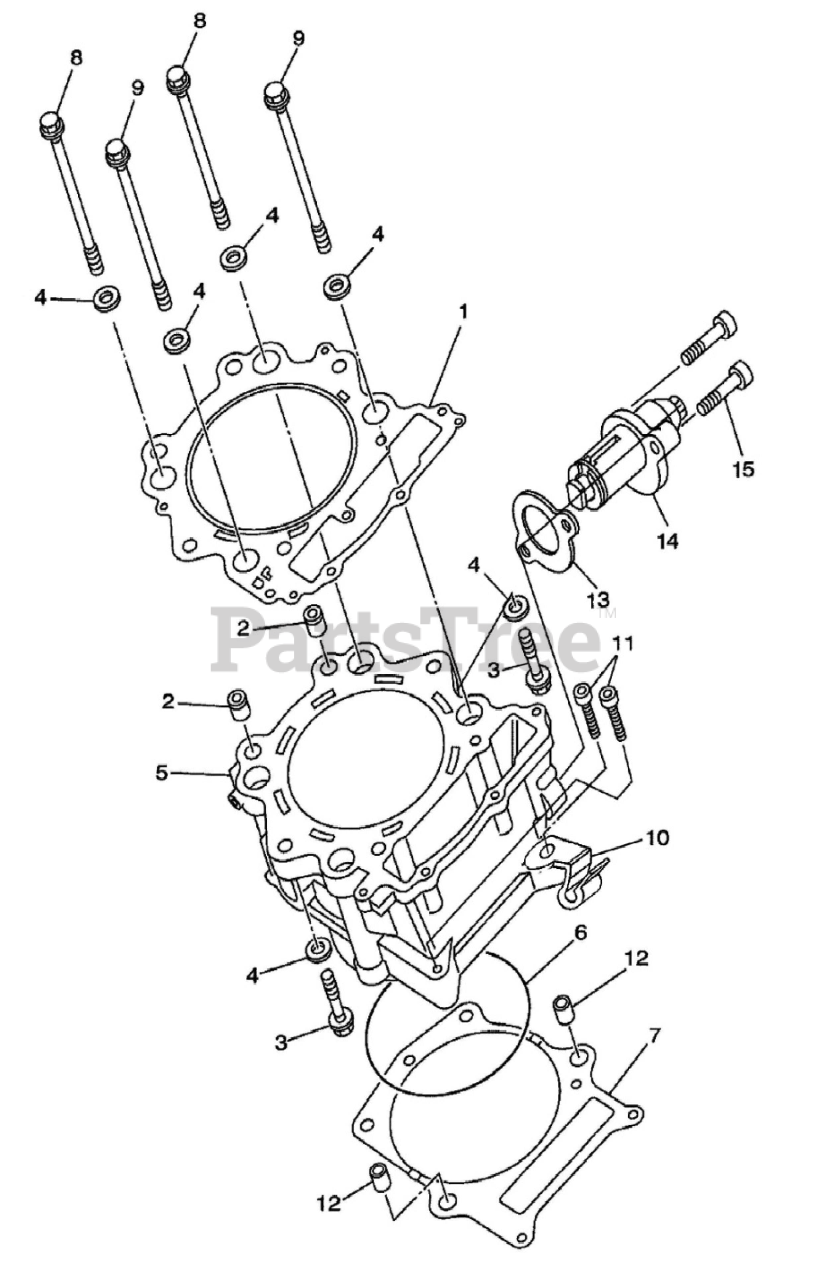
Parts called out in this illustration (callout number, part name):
1	Gasket,Cylinder Head
2	Pin,Dowel 12x16
3	Cylinder bolts M9x1.25x39
4	Washer 10x19x2
5	Cylinder Body assy
6	O-Ring 105.7x2.8
7	Gasket,Cylinder Body
8	Cylinder bolts M10x1.25x121
9	Cylinder bolt M10x1.25x128
10	Pipe Clamp II
11	Hex head cap screw M6x40
12	Pin,Dowel 14x16
13	Gasket,Tensioner
14	Tensioner
15	Hex head cap screw M6x25
